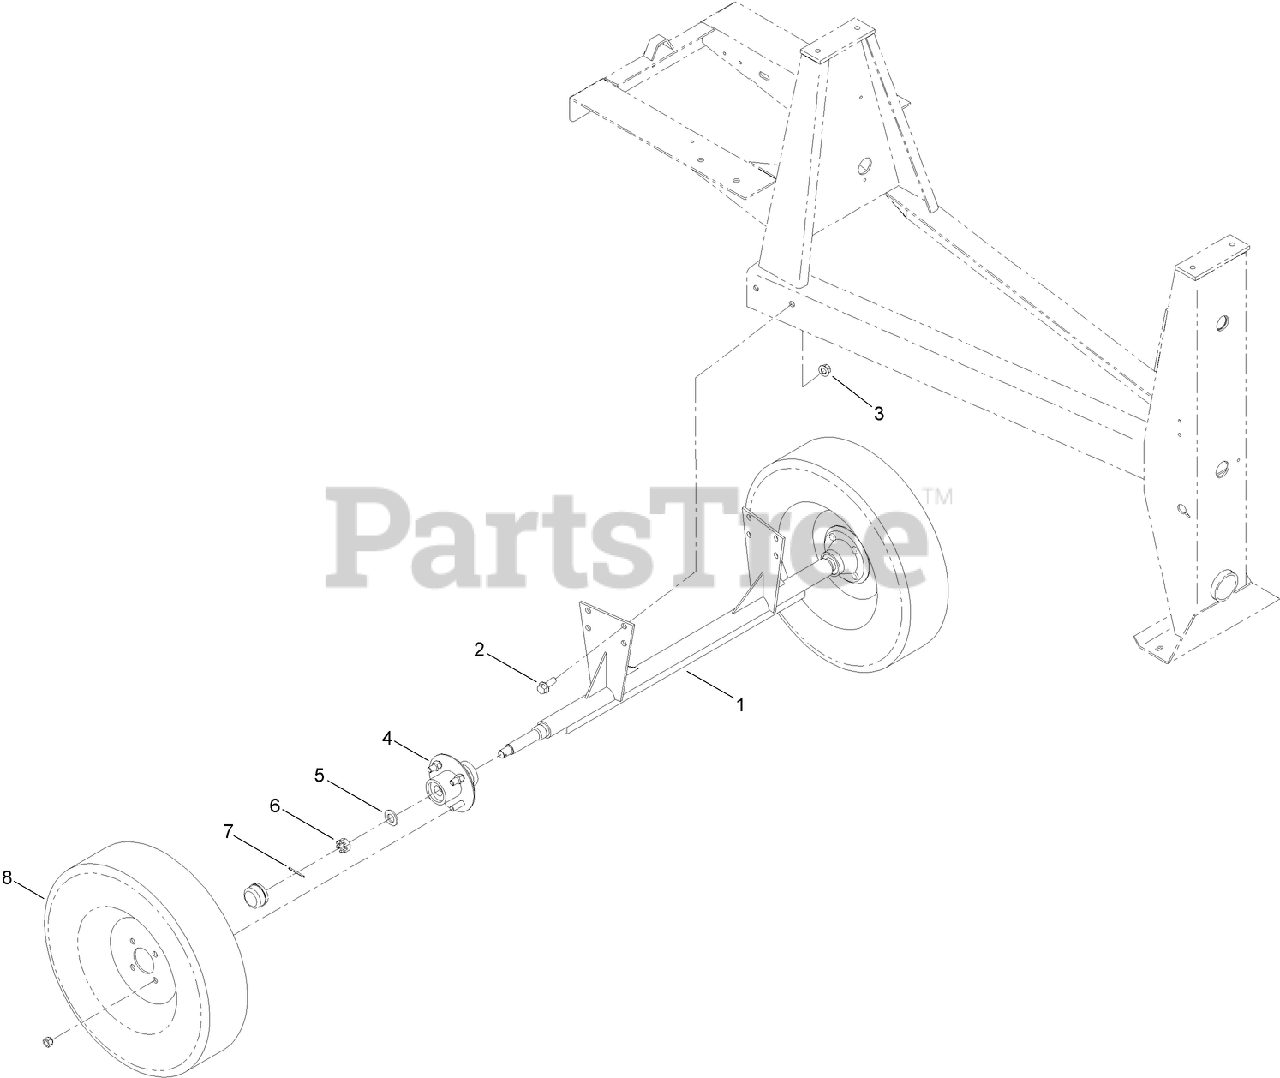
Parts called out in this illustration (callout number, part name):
2	SCREW-HHF
3	NUT-LOCK
4	HUB ASM
5	WASHER-FLAT
7	PIN-COTTER
8	TIRE AND RIM ASM
